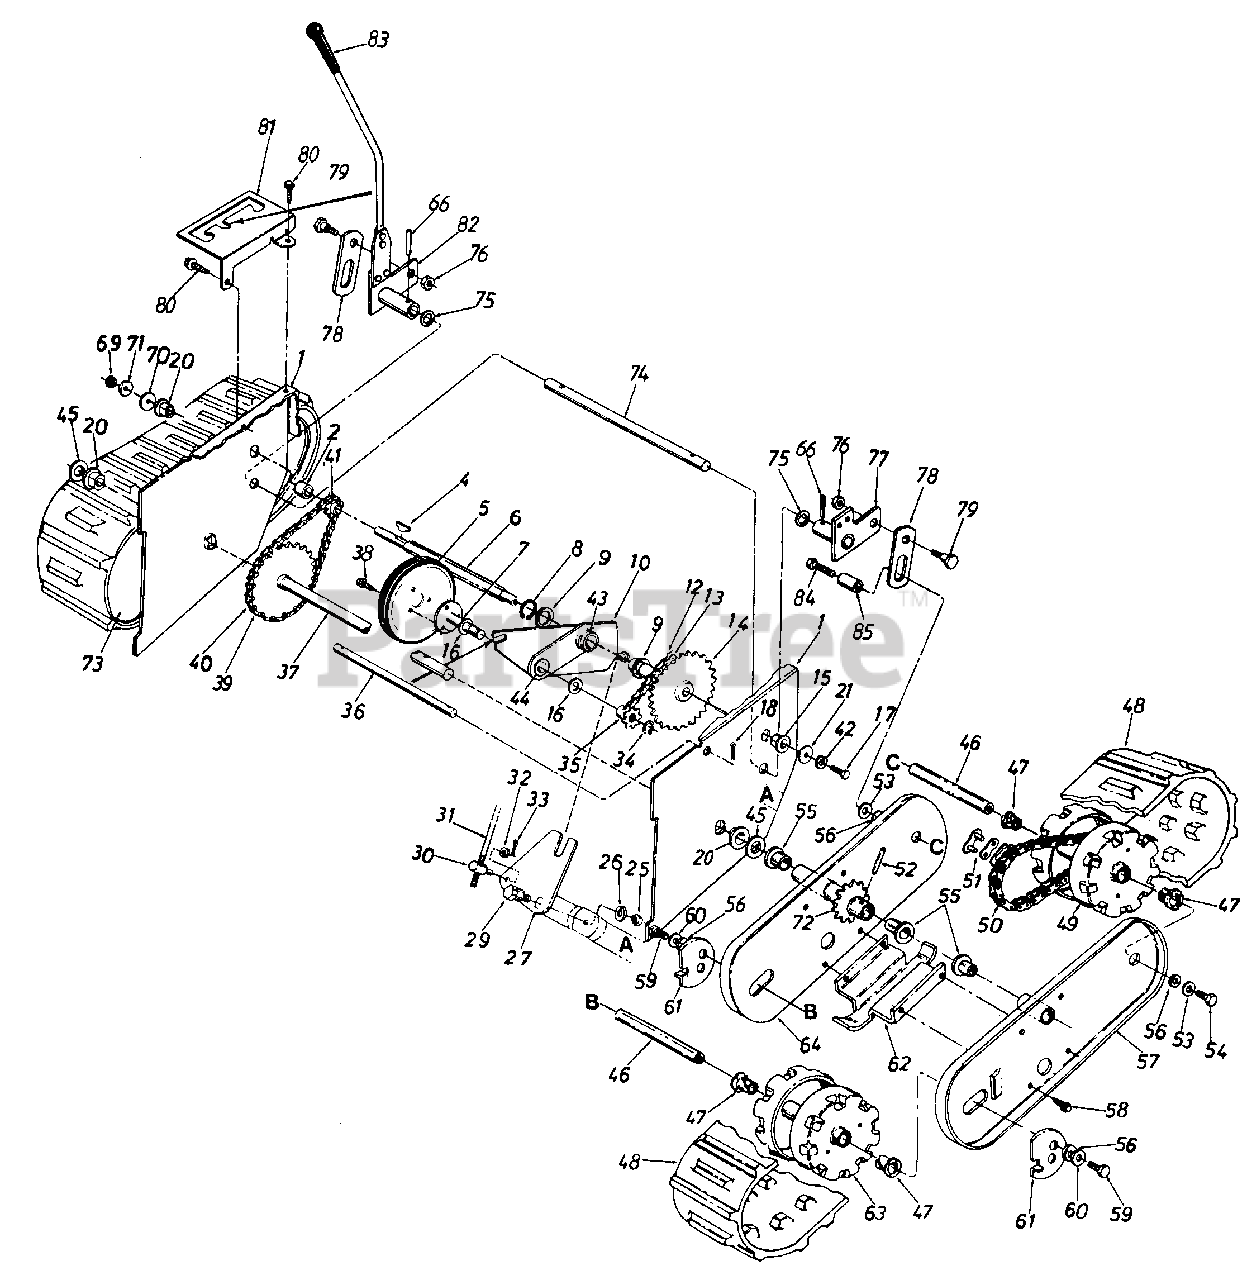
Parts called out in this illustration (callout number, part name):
1	FRAME ASSY
4	KEY-HI-PRO #4-3/32X5/8 DIA-HDN
5	WHEEL ASSY-FRICTION
6	SHAFT-HEX
7	PLATE ASSY-FRICTION WHEEL MTG
8	RING-SNAP FOR 1.00 DIA SHAFT
9	WASHER-FL-1.03 ID X 1.62 X .03 HD
10	BRACKET ASSY-SLIDING
12	CHAIN X 35 LINKS
13	#41 MASTER LINK 1/2 PITCH TYPEII
14	SPROCKET ASSY-32T
15	BEARING-FLANGE
16	WASHER-FL
17	SCREW-HEX 5/16-18 X .62
18	PIN-COTTER-3/32 DIA X .75
20	BEARING-FLANGE
21	WASHER-FL-.312 X 1.125 X .125
25	NUT-HEX JAM 3/8-18
26	WASHER-LOCK-3/8
27	BRACKET-LINKAGE
29	SCREW-SHLD .625 DIA X .163
30	FERRULE
31	ROD-SHIFT
32	WASHER-FL-.344 X .62
33	PIN-COTTER-3/32 DIA X .75
34	RING-C SNAP
35	SPROCKET-7T
37	AXLE ASSY-WHEEL
38	SCREW-HEX WASH SF TAPP
39	#420 CHAIN 1/2 PITCH X 39 LINKS
40	#420 MASTER LINK 1/2 PITCH TYPE II
41	SPROCKET-CENTER #41-8T
42	WASHER-LOCK-5/16
43	BEARING
44	BEARING-FLANGE .630 ID
45	WASHER-FL-.760ID X 1.49OD X .06HDN
46	SHAFT-WHEEL
47	BEARING-FLANGE
48	TRACK-SNOWTHROWER
49	WHEEL ASSY-DRIVE
50	#420 CHAIN 1/2 PITCH X 37 LINKS
51	#420 MASTER LINK 1/2 PITCH TYPE II
52	PIN-SPRING SPIRAL 1/4X1.5 HEAVY DT
53	WASHER-BELL .337 X .867 X .057
54	SCREW-HEX 5/16-24 X .62
55	BEARING-FLANGE
56	WASHER-FL
57	PLATE ASSY-OUTER-LH
58	SCREW-HEX WASH SF TAPP
59	SCREW-HEX 5/16-24 X .62
60	WASHER-BELL .337 X .867 X .057
61	ADJUSTER-TRACK
62	SHOE-SKID
63	IDLER ASSY-WHEEL
64	PLATE ASSY-INNER-LH
66	PIN-SPRING-SPIR 1/4 X 1.250
69	NUT-HEX INS L-1/2-20
70	WASHER-FL-.546 X 1.28 X .090
71	WASHER-BELL .505 ID X 1.00 OD
72	SPROCKET ASSY-17T
73	PLATE ASSY-INNER-RH
74	AXLE-TRACK LOCK
75	WASHER-FL
76	NUT-HEX CENTER L-3/8-16
77	ARM ASSY-PIVOT-LH
78	LINK-SLOTTED
79	SCREW-SHLD
80	SCREW-HEX HD TAP
81	PLATE-POS SELECTOR
82	HANDLE ASSY-LOCK
84	SCREW-HEX 5/16-24 X 1.25
85	SPACER
